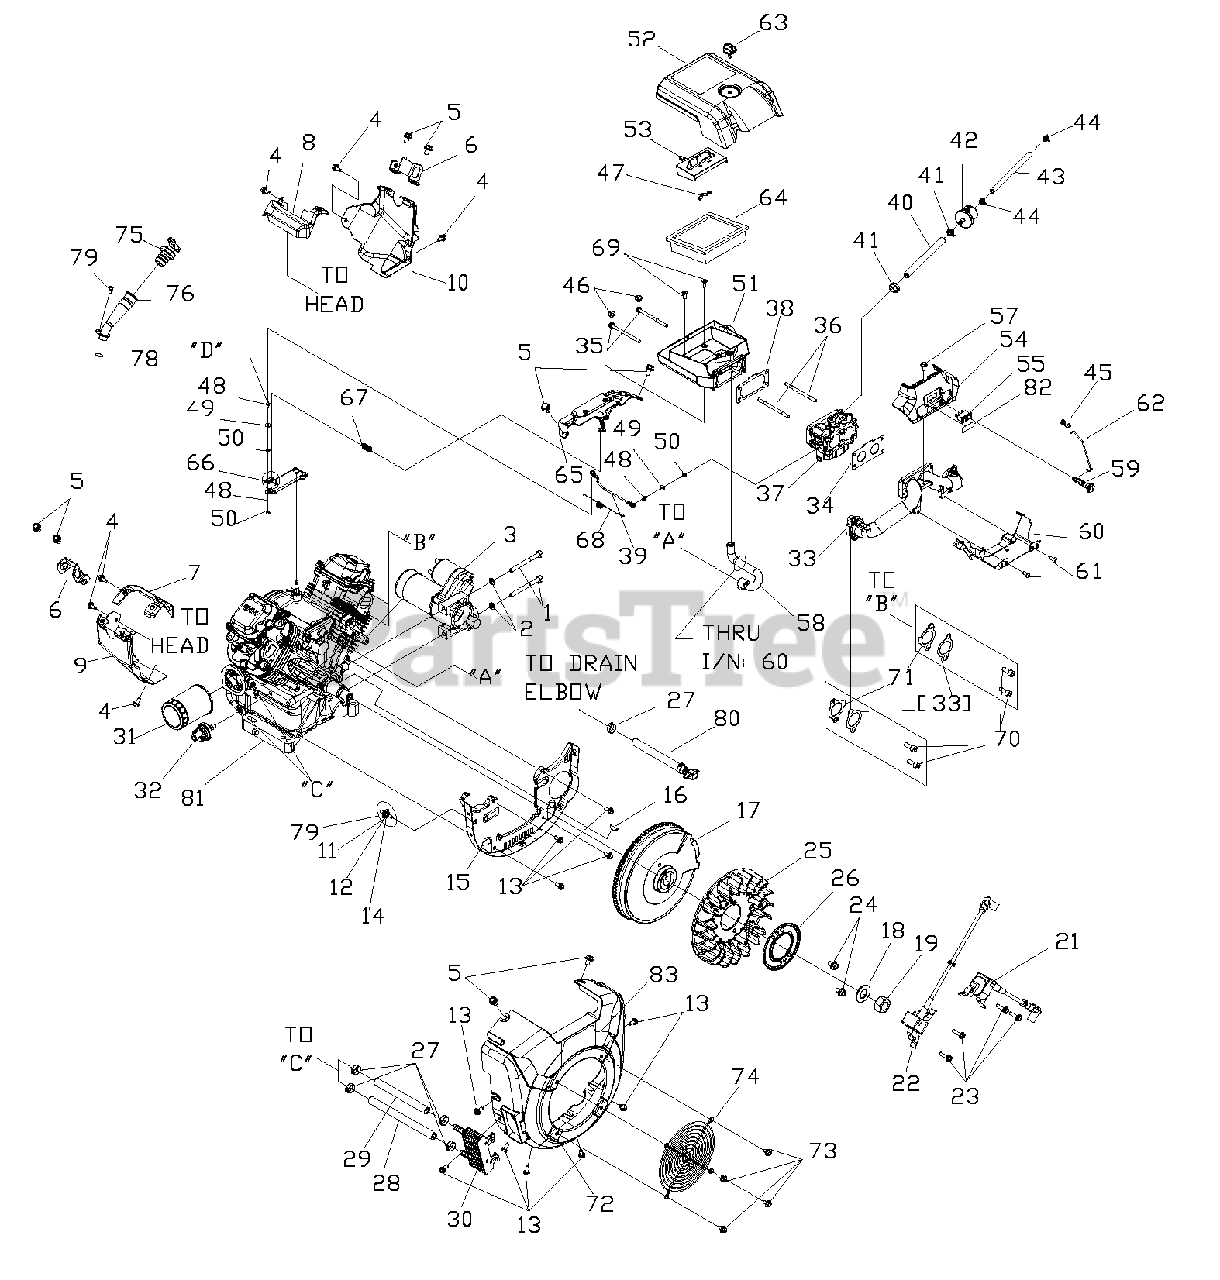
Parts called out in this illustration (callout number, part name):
1	SCREW HHC M8-1.25 X 85
2	WASHER LOCK M8-5/16
3	STARTER MOTOR GEAR REDUCED 1KW
4	SCREW HHFCS M6-1 X 12
5	SCREW HHFC M8-1.25 X 14
6	LIFTING HOOK GT530
7	WRAPER INNER CYL #2
8	WRAPPER INNER CYL #1
9	WRAPPER OUTER CYL #2
10	WRAPPER OUTER CYL #1
11	SCREW CONNECTOR
12	GROUND POST MOUNT BLOCK
13	SCREW HHFC M6-1.0 X 8
14	NUT HEX M5 X 0.8
15	BACKPLATE GT530
16	KEY WOODRUFF 4 X 19D
17	ASSY FLYWHEEL AND RING GEAR 29 DEG
18	WASHER BEL V-20 X 2.2
19	HEX NUT METRIC
21	ASSY IGN COIL W/DIODE GTH530 CYL 1
22	ASSY IGN COIL W/DIODE GTH530 CYL 2
23	SCREW HHC M6-1.25 X 12
24	SCREW HHFCS M8-1.25 X 12
25	FAN FLYWHEEL
26	PLATE FAN GV-990
27	CLAMP HOSE OETIKER STEPLESS 18.5
28	HOSE 3/8" PUSH ON (191 MM)
29	HOSE 3/8" PUSH ON (152 MM)
30	OIL COOLER GT530
31	FILTER OIL 90MM NO BRAND
32	SWITCH LOW OIL PRESSURE
33	MANIFOLD INTAKE GT530
34	GASKET INTAKE MANIFOLD TO CARBURETOR
35	BOLT CARB MOUNT
36	STUD M6-1 X 90 DRI-LOC
37	CARBURETOR
38	GASKET AIRBOX TO CARBURETOR
39	ASSY GOVERNOR ROD
40	HOSE 1/4" GREENBAR SAE30R7 6"
41	CLAMP HOSE BAND 0.530
42	FILTER, FUEL
43	FUEL HOSE 160MM LONG
44	CLAMP HOSE BAND 0.409
45	BUSHING GOVERNOR ROD
46	NUT FLANGE M6-1.0 NYLOK
47	SPRING SUMMER / WINTER VALVE
48	BALL STUD 8MM
49	SPACER ROD THROTTLE
50	NUT HEX LOCK M3-0.5 NY INSERT
51	BASE AIRBOX GTH530
52	COVER AIRBOX GTH530
53	VALVE SUMMER / WINTER
54	COVER FRONT GTH530 CONSTANT SPEED
55	SWITCH MOMENTARY (OFF) - ON
57	SCREW HHFCS M6-1.0 X 10
58	BREATHER HOSE GTH530
59	KNOB CHOKE GTH530
60	BAFFLE CENTER GTH530 PORTABLE
61	SCREW BHSC M6-1.0 X 12
62	ROD MANUAL CHOKE GTH530
63	KNOB AIRBOX QUARTER-TURN
64	AIR FILTER ELEMENT
65	ASSY SPEED CONTROL
66	ASSY GOVERNOR LEVER GT530
67	SPRING GOVERNOR GTH530
68	SPRING ANTI-LASH GTH530
69	SCREW PFHM M6-1.0 X 12
70	SCREW SHC M8-1.25 X 20
71	GASKET INTAKE
72	BLOWER HOUSING
73	SCREW HHFCS M6-1.0 X 10
74	GUARD FAN
75	ASSY FLAT DIPSTICK
76	ASSY OIL CHECK & FILL
77	SCREW HHSW M5-0.8 X 10
78	O-RING 9/16 X 3/4 X 3/32
79	ASSY GROUND WIRE CONNECTOR
80	ASSY OIL DRAIN HOSE
81	ASSY BLOCK GTH530 GAS PORT
82	DECAL IGNITION
83	DECAL ENGINE XG 10KW
